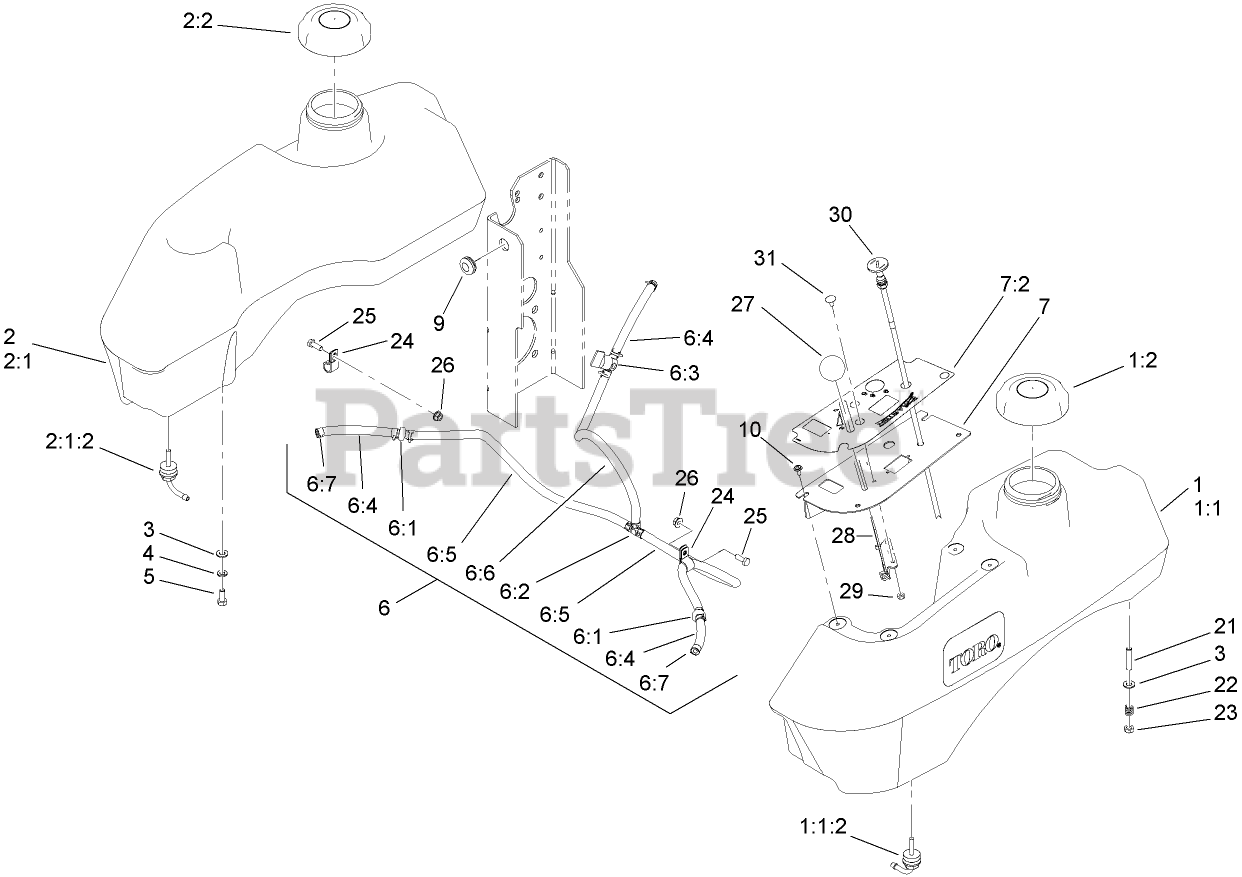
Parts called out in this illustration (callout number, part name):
1	LH FUEL TANK SERVICE KIT
1:1	LH FUEL TANK ASM
1:1:2	FITTING-FUEL, BULKHEAD
1:2	CAP-FUEL, GAS
2	RH FUEL TANK SERVICE KIT
2:1	RH FUEL TANK ASM
2:1:2	FITTING-FUEL, BULKHEAD
2:2	CAP-FUEL, GAS
3	WASHER-PLAIN
4	WASHER-LOCK
5	SCREW-HH
6	FUEL LINE ASM
6:1	VALVE-CHECK, FUEL
6:2	FITTING-TEE, BARBED
6:3	VALVE-FUEL
6:4	HOSE-FUEL
6:5	HOSE-FUEL
6:6	HOSE-FUEL
7	CONTROL PANEL ASM
7:2	DECAL-PANEL, CONTROL
9	GROMMET
10	SCREW-PPH
22	SPRING-TANK, FUEL
23	NUT-LOCK, NI
24	CLIP-LOOM
25	SCREW-HH
26	NUT-HF
27	KNOB-BALL
28	THROTTLE CABLE ASM
29	NUT-LOCK, NI
30	Control-Choke, Push / Pull
31	BOLT-CARR
